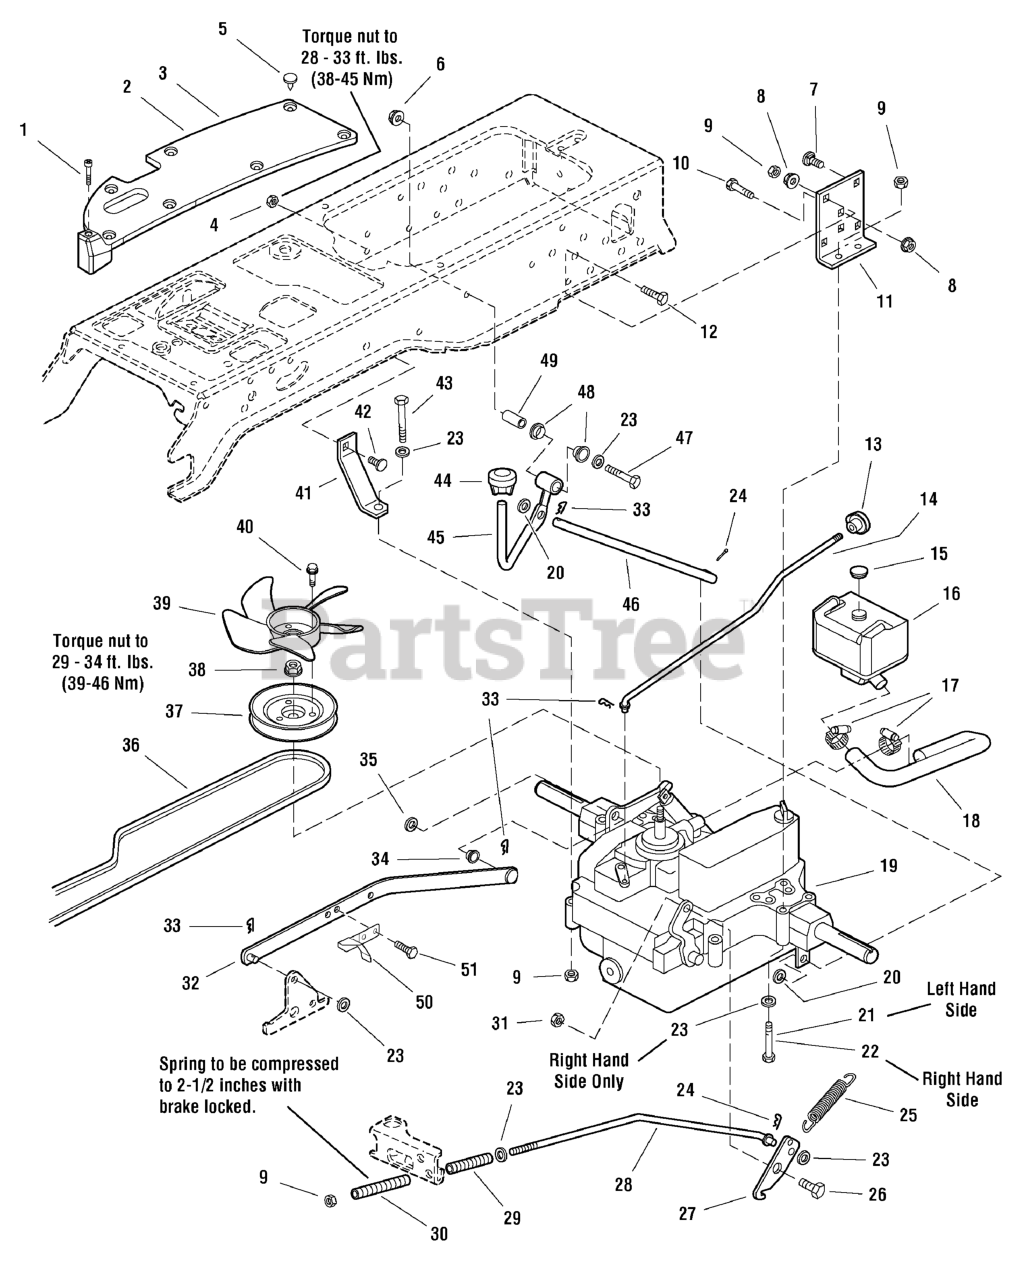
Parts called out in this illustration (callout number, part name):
1	SCREW, Pan Head Trox Taptite, 1/4-20 x 1-1/4
2	PAD, Footrest, RH
3	PAD, Footrest, LH, Differential Lock
4	NUT, Hex KEPS, 5/16-18
5	FASTENER, 3/4 Long Stem Plastic
6	NUT, Hex Flange Whiz Lock, 3/8-16, Large
7	CARRIAGE BOLT, 3/8-16 x 1
8	NUT, Hex KEPS, 3/8-16
9	NUT, Hex Flange ESNA, 3/8-16
10	CAPSCREW, Hex Head, 3/8-16 x 1
12	CAPSCREW, Hex Head 3/8-16 x 1-1/2
13	KNOB, Internal Thread 1/4-20
14	ROD, Free Wheel, 18-3/16 Long
15	CAP, Expansion Tank Plastic
16	TANK, Oil Natural
17	CLAMP, Hose Worm Drive # 20 1 3/4"
18	HOSE, Expansion Tank Formed
19	TRANSMISSION ASSEMBLY, K71E
20	WASHER, 7/16
21	CAPSCREW, LH, Hex Head, 3/8-16 x 3-1/4
22	CAPSCREW, RH, Hex Head, 3/8-16 x 3-3/4
23	WASHER, 3/8
24	PIN, Cotter, 3/32 x 3/4
25	SPRING, Extension
26	CAPSCREW, Hex Head, 1/2-13 x 1
27	ARM, Brake
28	ROD, Brake
31	NUT, Hex Lock, 1/2-13
32	ARM & WELD, PINS ASSEMBLY, Control K71
33	PIN, Quick
34	BEARING, 1/2 x 9/16 x 11/32, Nylon
35	WASHER, 1/2
36	V-BELT, Transmission Drive
37	PULLEY & HUB ASSEMBLY, Transmission
38	NUT, Hex Flange, M12-1.75, Nylon Insert
39	FAN, 5 Blades, Nylon, 3-Holes
40	CAPSCREW, Hex Washer Head Taptite, 1/4-20 x 1-1/8
41	BRACKET, Transmission
42	BOLT, Carriage, Short Neck, 5/16-18 x 1
43	CAPSCREW, Hex Head, 3/8-16 x 2-3/4
44	KNOB, Hole, 1/2 x 1-3/4, 2-11/16
45	ROD & TUBE ASSEMBLY, Differential Lock, Pedal
46	ROD, Differential Lock, K71
47	CAPSCREW, Hex Head 3/8-16 x 2-1/4
48	BUSHING, 5/8 x 3/4 x 13/32, Powder Metal
49	SPACER, 1 1/2" Long Hardened
50	ACTUATOR, Switch
51	CAPSCREW, Hex Head Taptite, 5/16-18 x 1/2
